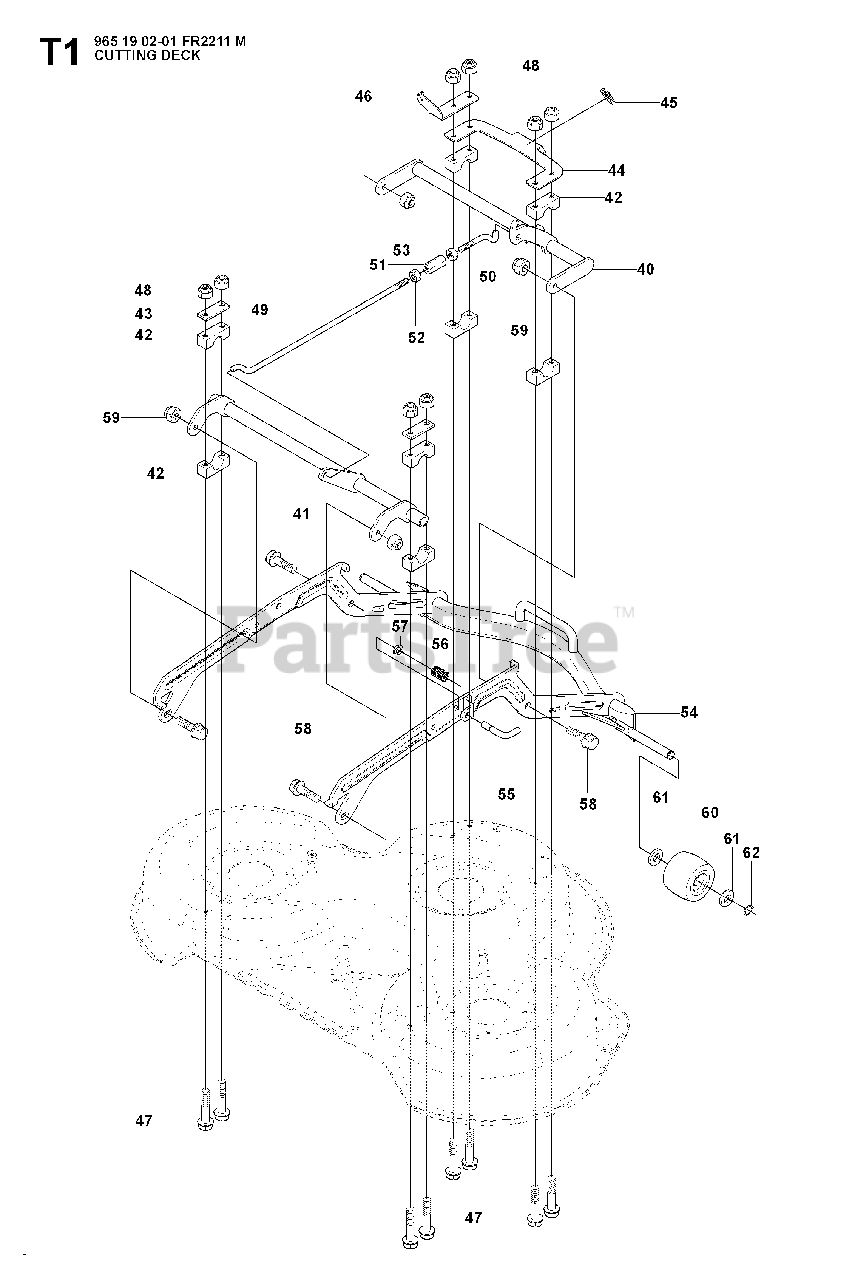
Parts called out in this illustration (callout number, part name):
48	LOCKNUT M8
59	LOCKNUT M8
60	DECK ROLLER, FRONT
62	RETAINING RING SGA 15
